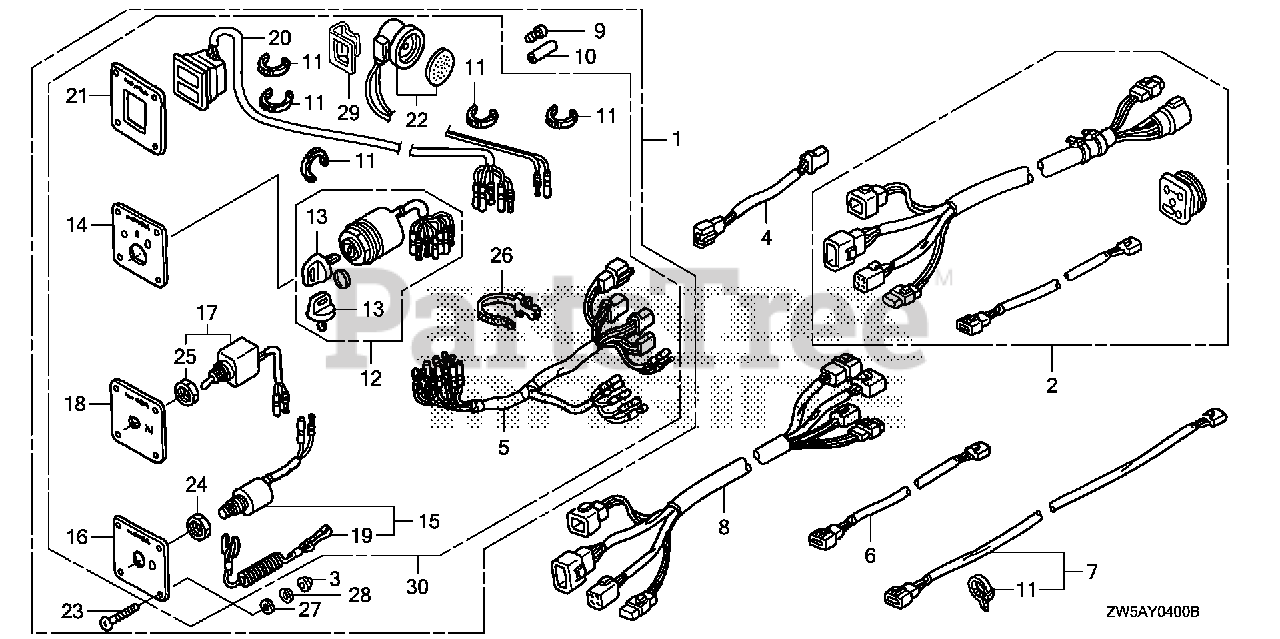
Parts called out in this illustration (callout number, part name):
2	CABLE KIT, SWITCH INDICATOR
3	NUT, FLANGE (5MM)
4	SUB-HARNESS ASSY., POWER TRIM-TILT (A)
5	HARNESS ASSY., SWITCH PANEL
6	CABLE ASSY., EXTENSION (3P 7FT)
7	CABLE ASSY., EXTENSION (3P 30FT)
8	CABLE ASSY., EXTENSION (17P 7FT)
9	PLUG, CONNECTOR (INNER)
10	PLUG, CONNECTOR (OUTER)
11	TIE, CABLE (2.4X92) (NATURAL)
12	SWITCH ASSY., COMBINATION
13	KEY ASSY., COMBINATION SWITCH (35100-ZV5-003 ONLY)
14	PANEL, SWITCH
15	SWITCH ASSY., EMERGENCY STOP
16	PANEL, EMERGENCY STOP SWITCH
17	SWITCH ASSY., SOLENOID
18	PANEL, SOLENOID
19	WIRE, EMERGENCY
20	LAMP ASSY., INDICATOR (2-LED)
21	PANEL, INDICATOR
22	BUZZER, WARNING
23	SCREW, PAN (5X40)
24	NUT, HEX. (16MM)
25	NUT, HEX. (12MM)
26	BAND, WIRE HARNESS (150MM) (NATURAL)
27	WASHER, PLAIN (5MM)
28	WASHER, SPRING (5MM)
29	BRACKET, BUZZER
30	PANEL ASSY., CONTROL (TYPEB)
